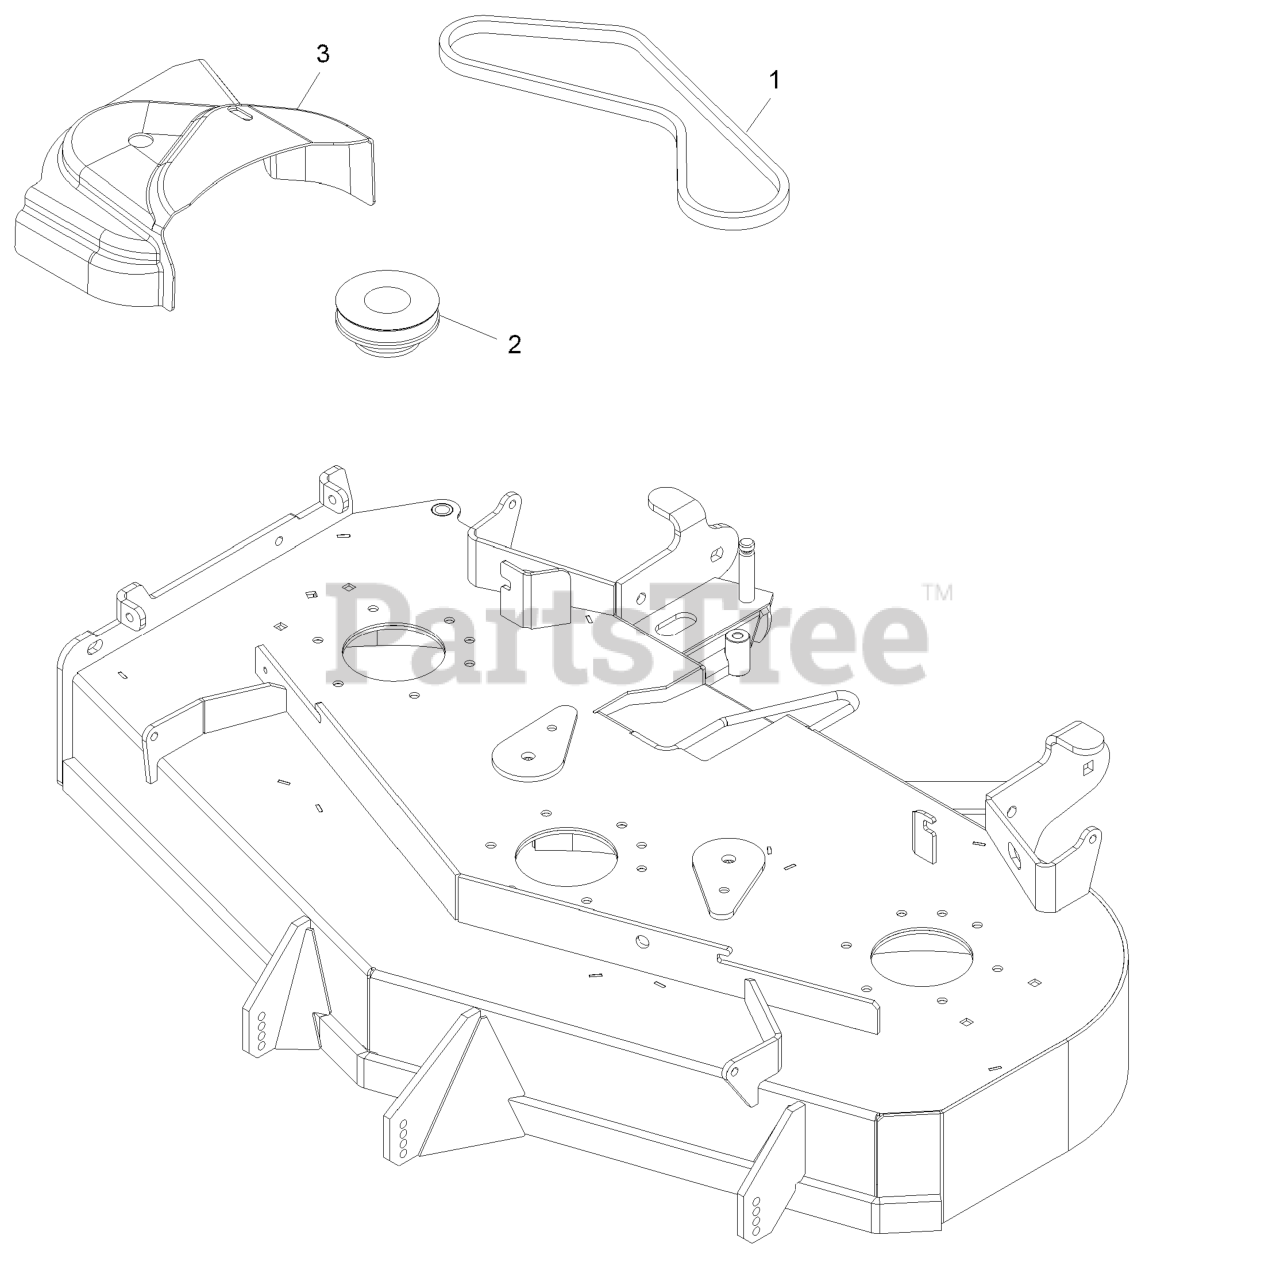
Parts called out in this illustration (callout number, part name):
1	BELT-BLOWER
2	SHEAVE,DRIVE LZUV 486
3	COVER,BELT UV 48
